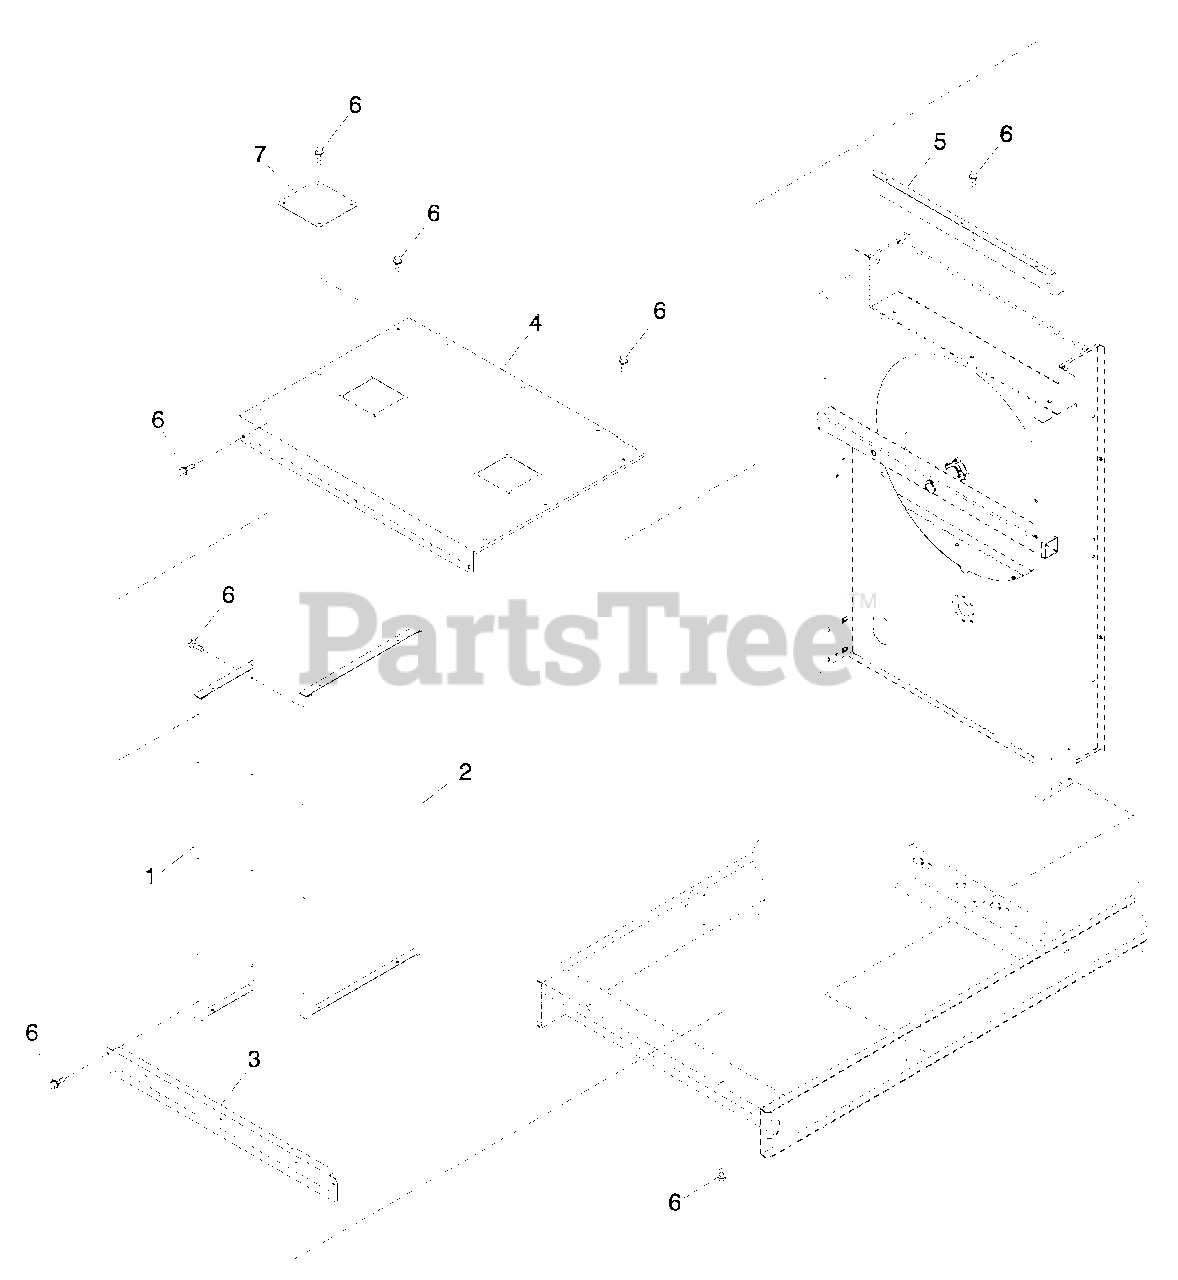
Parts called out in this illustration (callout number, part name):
1	PANEL C5 FRONT SIDES
2	PANEL C5 REAR SIDES
3	PANEL LOWER FRONT
4	PANEL C5 TOP
6	SCREW THF M6-1 X 16 N WA Z/JS
7	ACCESS COVER 160 X 170 GALV
8	SCREW THF M6-1 X 16 N WA Z/JS
